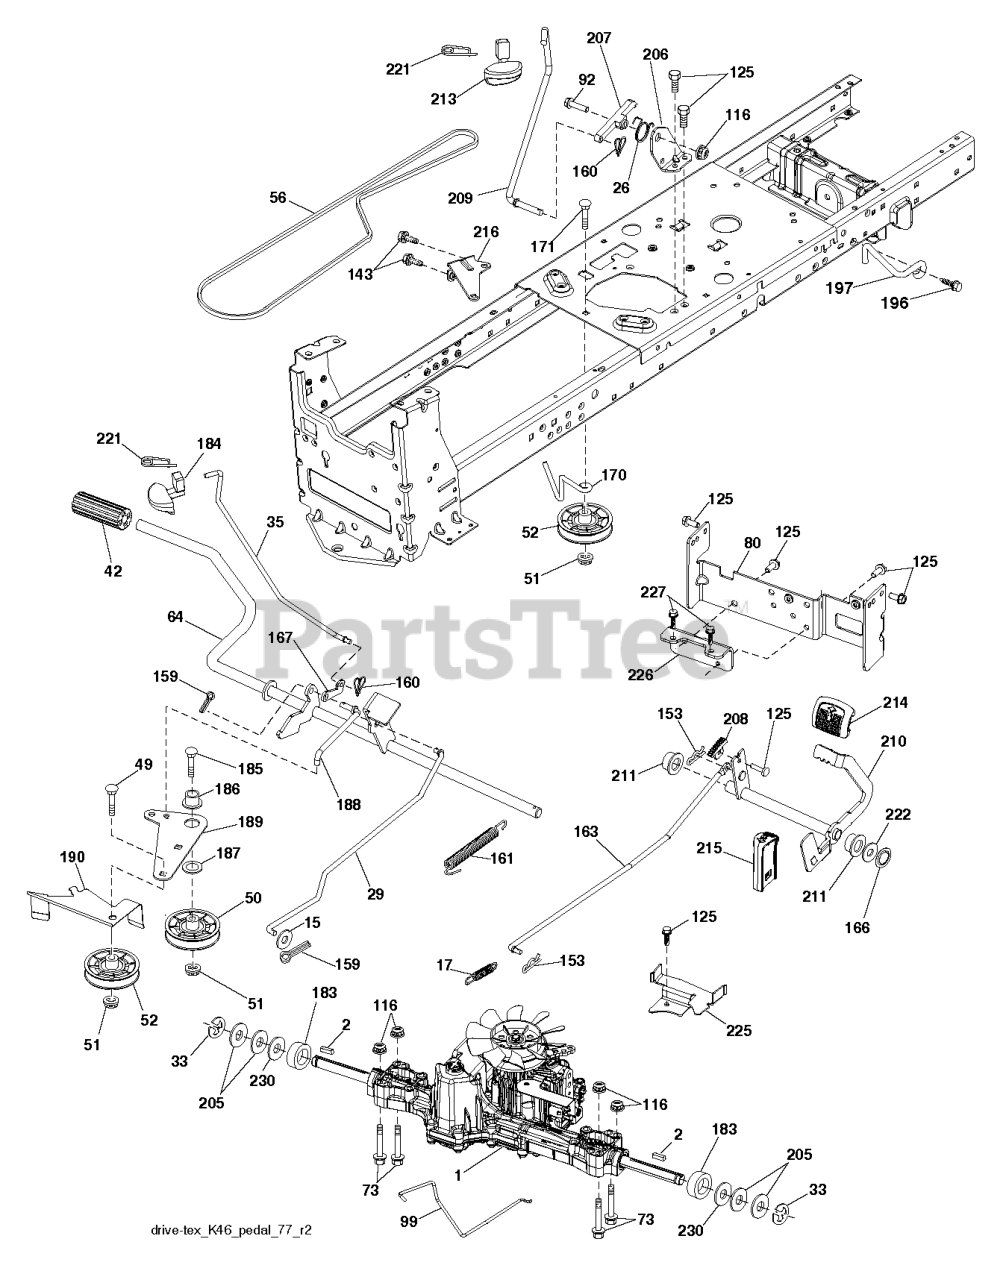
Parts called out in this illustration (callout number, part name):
2	SQUARE KEY
15	WASHER
17	SPRING.BRAKE.K46.GREEN
26	SPRING.RETURN.CRUISE
29	ROD.BRAKE.K46
35	ROD.BRAKE.PARTK.HUSQ.TEX
42	PEDAL COVER T
50	IDLER.FLAT.910.OFFSET
51	NUT LOCK FLG 3/8-16 UNC
52	IDLER.V-GROOVE.910.OFFSET
56	V-BELT.MOWER.92.40.42/K46
64	SHAFT.ASM.PEDAL.BRK.CNTR
73	BOLT
80	STRAP.TORQUE.K46.K57R.TT
92	BOLT
99	ROD.SPRING.BYPASS.K46.LT.Z
116	NUT LOCK HEX FLANGE 5/16-18
125	SCREW
143	SCREW LT
153	RETAINER M
159	COTTER PIN
160	RETAINER CLIP
161	SPRING, RETURN LT
163	ROD.CONTROL.PEDAL.K46
166	NUT.PUSH.625
167	LATCH.BRAKE.SPRING
170	KEEPER.V-IDLER.CENTER.
171	BOLT
183	SPACER AXLE
184	RB HANDLE.PARKG.BRK.HUS/PRED
186	SPACER.RETAINER
187	WASHER 12/32X2X10GA
188	RP.LINK.CLUTCH.GROUND.DRIVE
189	BELLCRANK.GROUND.DRIVE.TEX.
190	KEEPER.BELLCRANK.DRIVE
196	SCREW 3/8-16X1
197	LINK.CLUTCH.ANIT-ROTAT
206	BRKT.MOUNT.LATCH.CRUIS
207	LATCH.CONTROL.CRUISE
208	GEAR.SECTOR.CONTROL.CR
209	ROD.CONTROL.CRUISE.GT.
210	ROCKER.ASM.PEDAL.CONTR
211	BEARING.NYLON
213	KNOB.CONTROL.CRUSIE.HU
214	PEDAL.FORWARD.PAD.TEX
215	PEDAL.REVERSE.TEX.GT.4
216	BRACKET.PULLEY.IDLER.W/TEX
221	RETAINER.SPRING.CLIP.H
222	WASHER 21/32 X 1-1/4 X 10 GA.
225	KEEPER.BELT.TRANSAXLE.K46
226	BRACKET.MOUNT.TORQUE.K46.TLT
227	SCREW.THDROL.5/16-18X3/4.TTY
230	WASHER.HARDENED
